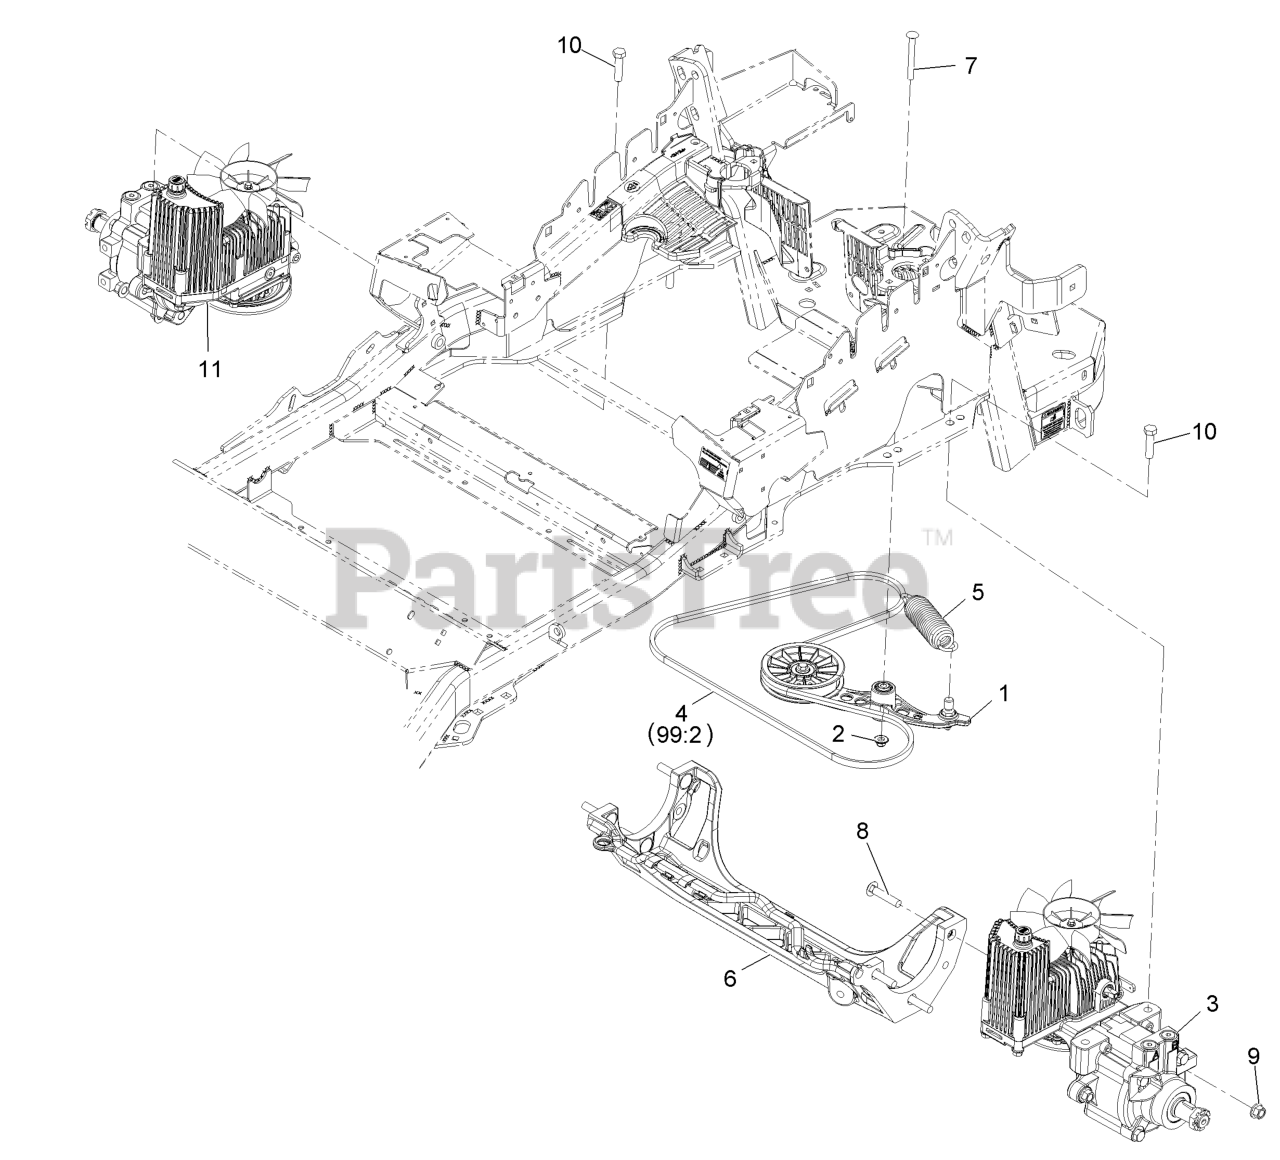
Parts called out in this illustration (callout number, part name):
1	PUMP IDLER ASM
2	Nut-Nyloc 3/8-16 Flg
4	BELT
5	SPRING-EXTENSION
7	BOLT-SHOULDER, CARRIAGE 3/8-16 X 3 1/2
8	SCREW-CARR
9	Nut-Lock 1/2-13
10	SCREW-HH
99:2	BELT
